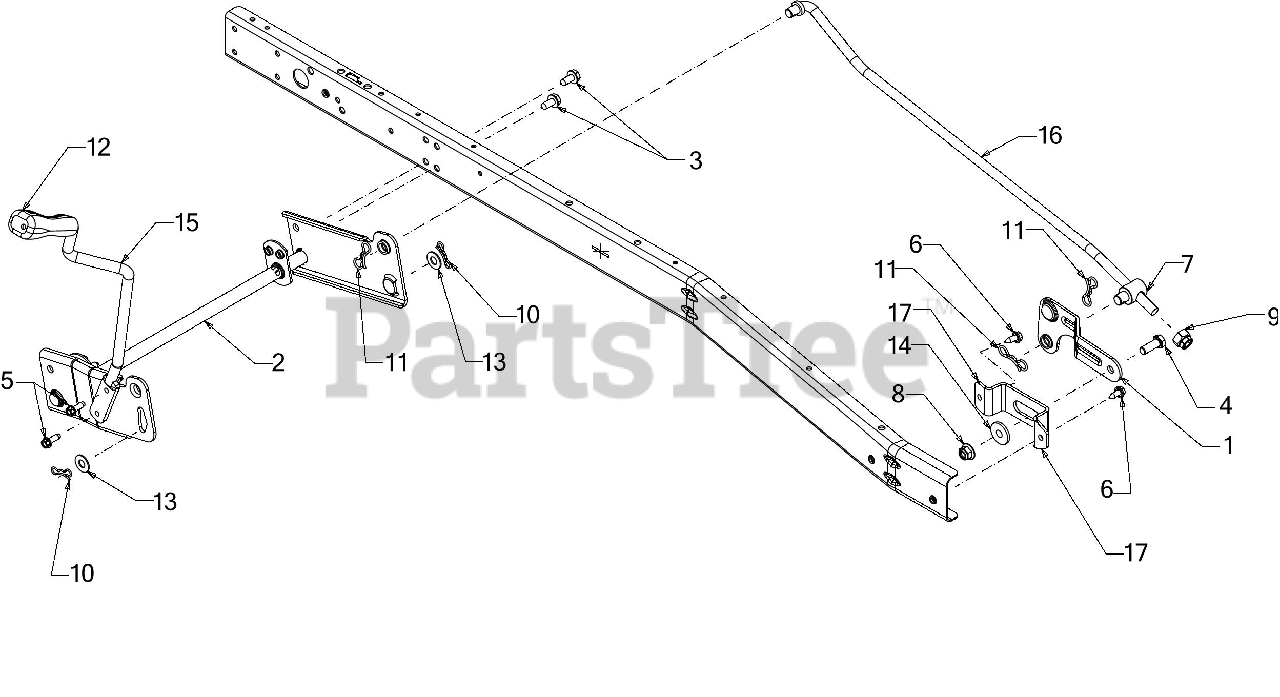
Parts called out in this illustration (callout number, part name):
1	FRONT BRACKET ASSEMBLY
2	LIFT SHAFT ASSEMBLY
3	SCREW 5/16-18 x .750
4	SCREW 3/8-16 x 1 GR5
5	SCREW 1/4-20 x .750
6	SCREW 1/4-20X.625
7	FERRULE
10	BOW TIE COTTER PIN 1/4-5/16
11	PIN:COTTER
12	HANDLE GRIP
13	FLAT WASHER
14	SHOULDER SPACER
15	DECK LIFT ROD
16	DECK LINK ROD
17	DECK HANGER BRACKET (LH)
